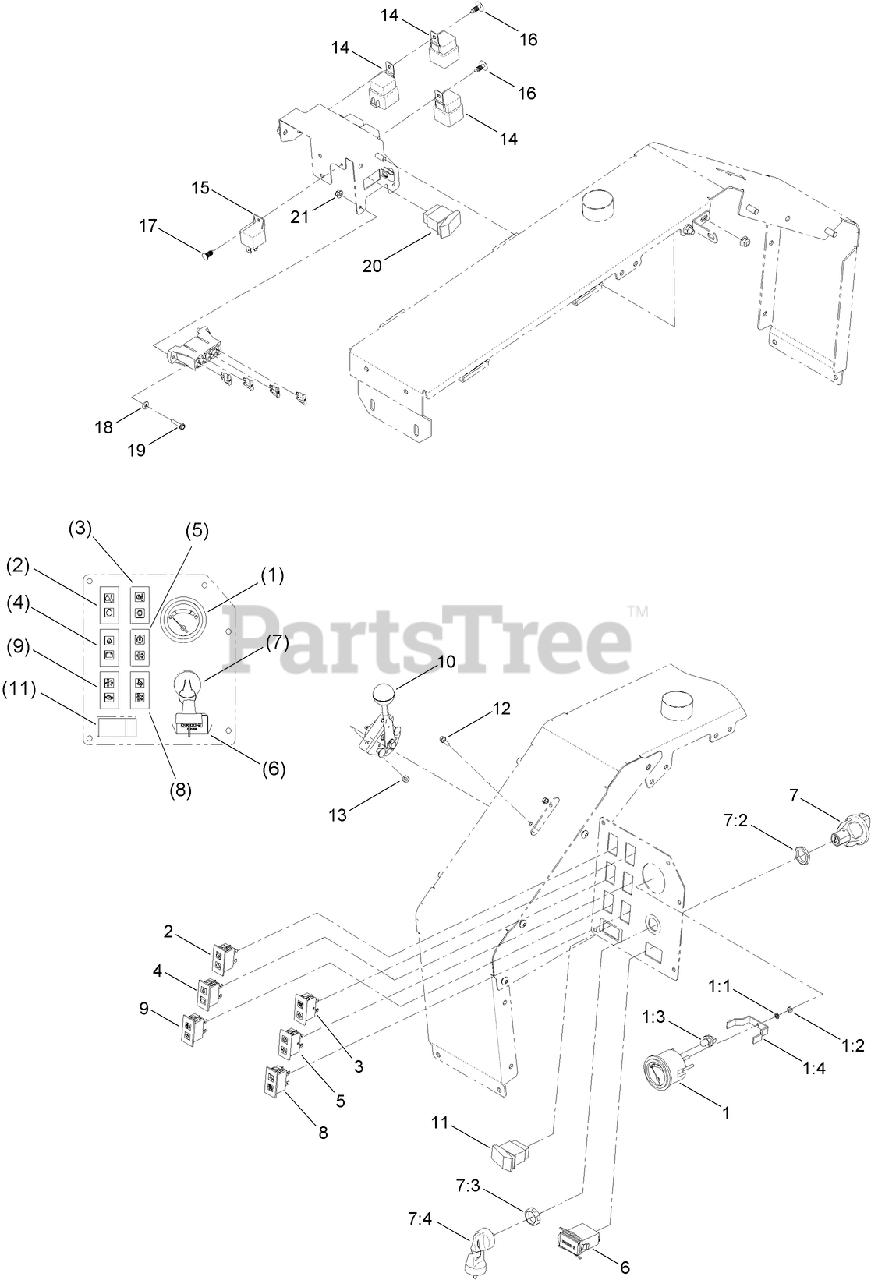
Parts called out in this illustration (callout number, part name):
1	GAUGE-FUEL
1:1	WASHER-LOCK, INT
1:2	NUT-HEX
1:3	Bulb And Lamp ASM
1:4	BRACKET-GAUGE
2	LIGHT CLUSTER ASM
3	LAMP-WARNING
4	LIGHT CLUSTER ASM
5	LAMP-WARNING
6	METER-HOUR
7	IGNITION SWITCH ASM
7:2	NUT-HEX
7:3	NUT-FACE
7:4	IGNITION KEY SET
8	LAMP-WARNING
9	LAMP-WARNING
10	THROTTLE-SENSOR, ROTARY
11	SWITCH
12	SCREW-HWH
13	NUT-LOCK, NI
14	RELAY
15	RELAY-POWER
16	PLUG-PLASTIC
17	PLUG-PLASTIC
18	WASHER-FLAT
19	SCREW-HWH
20	SWITCH
21	NUT-HF
